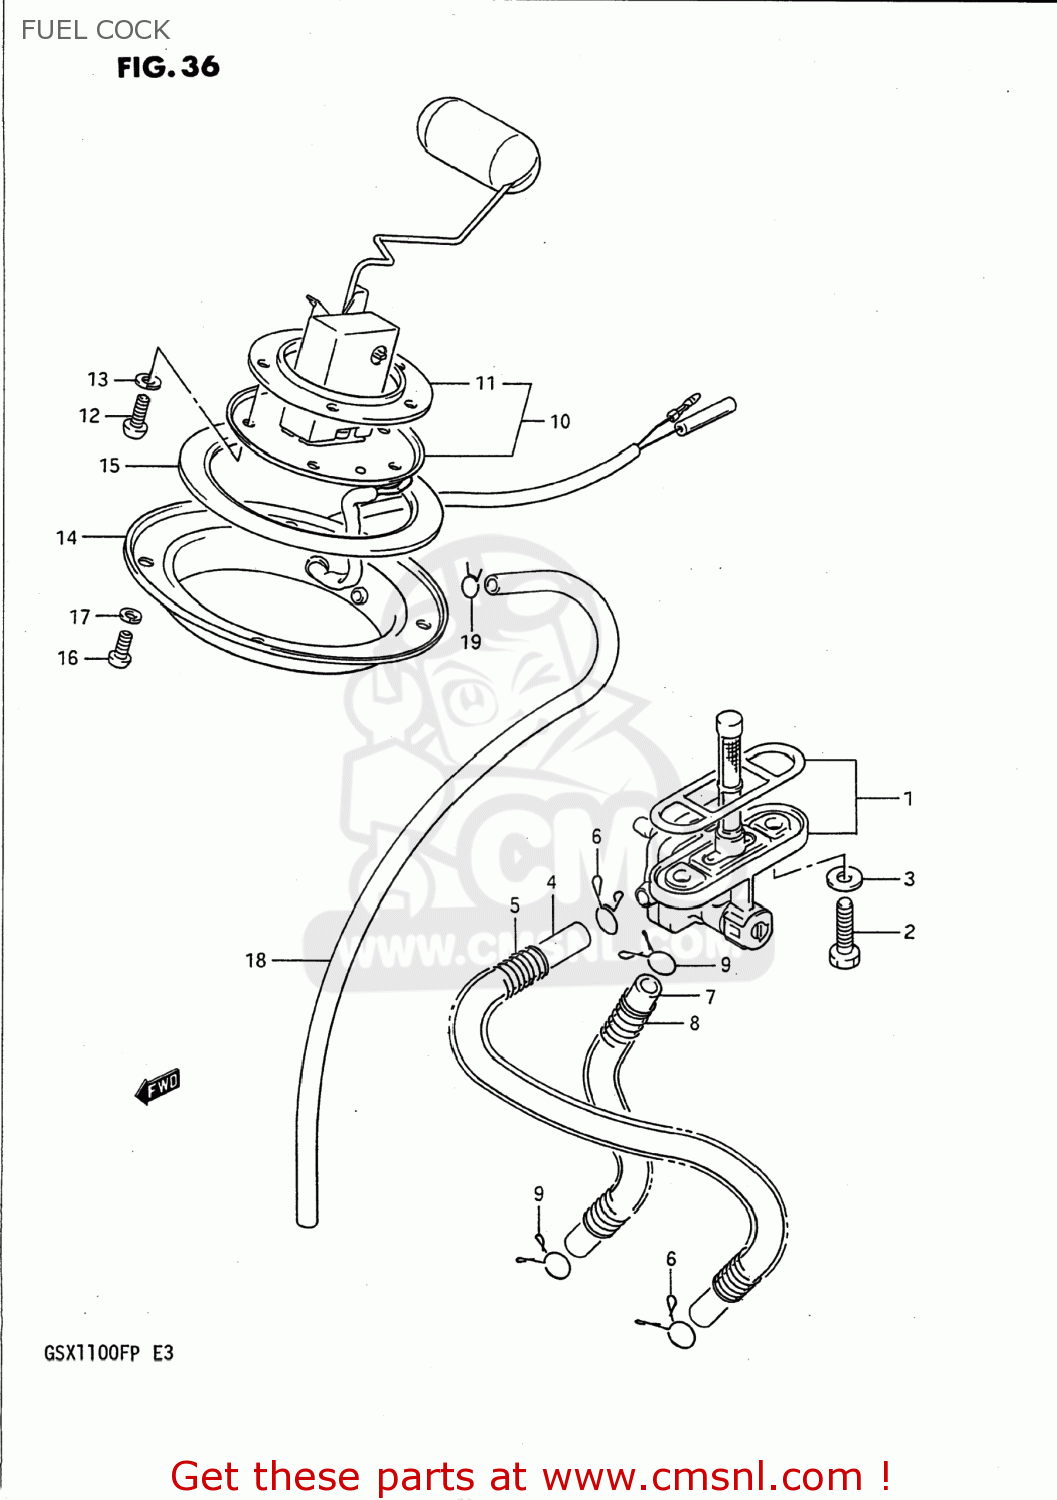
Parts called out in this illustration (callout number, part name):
1	COCK ASSY,FUEL
2	BOLT(6X20)
3	GASKET(5.8X13X1.2) (NAS)
4	HOSE
5	SPRING
6	CLIP
7	HOSE,FUEL NO.3
8	SPRING
9	CLIP
10	GAUGE ASSY,FUEL LEVEL SENDER
11	GASKET,FUEL LEVEL GAUGE (NAS)
12	BOLT
13	LOCK WASHER
14	PLATE,FUEL DRAIN
15	GASKET,FUEL DRAIN PLATE (NAS)
16	SCREW
17	LOCK WASHER
18	HOSE(5X8.2X2000)
19	CLIP
